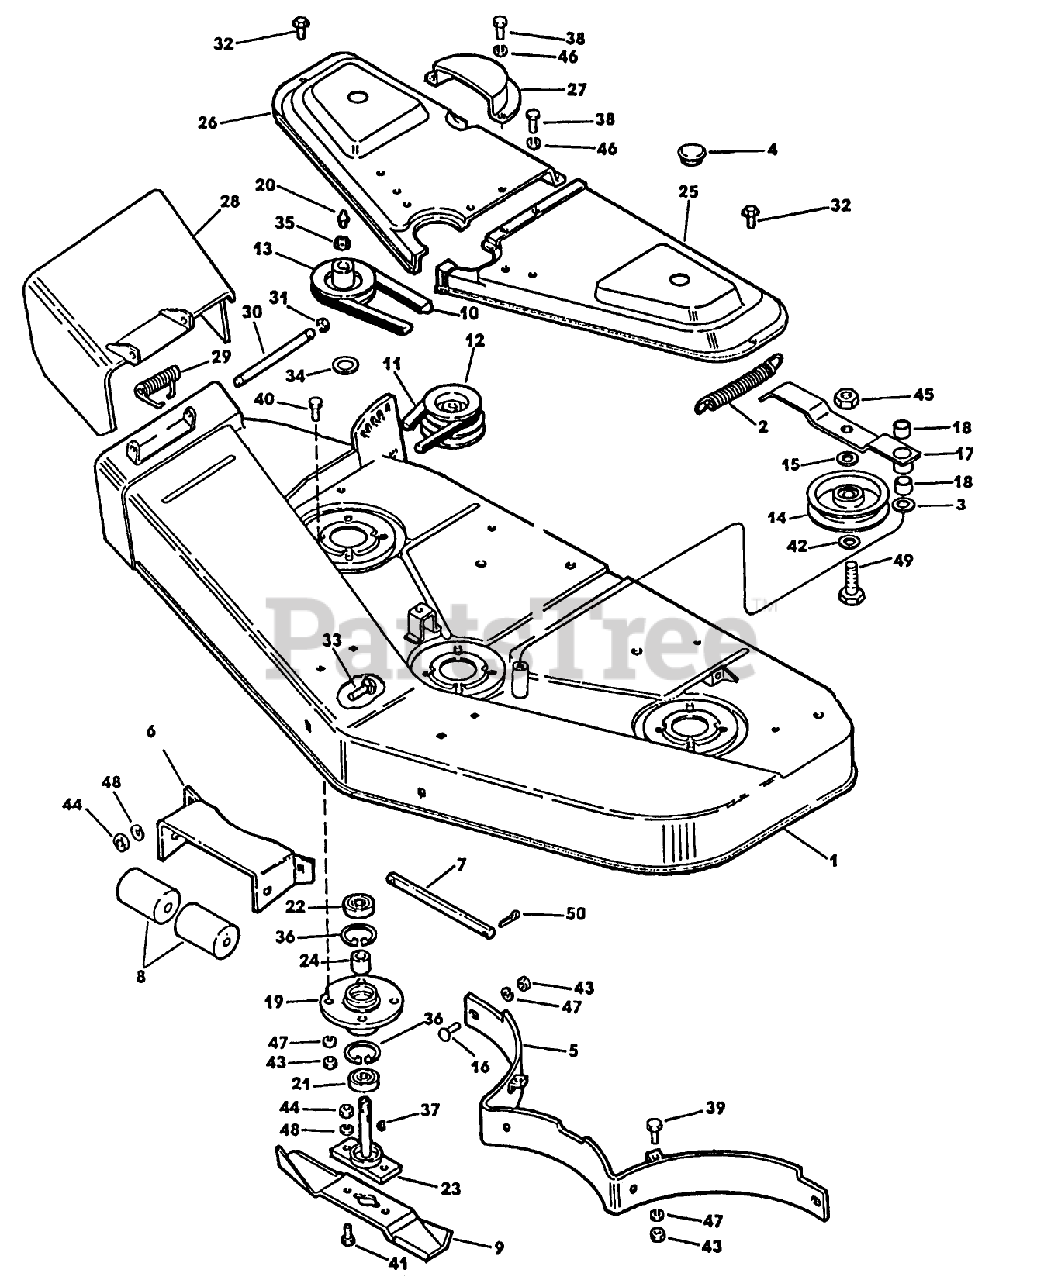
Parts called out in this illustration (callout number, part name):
2	SPRING
4	PLUG - BELT COVER
7	SHAFT
8	ROLLER
10	V-BELT
11	V-BELT T
14	PULLEY - IDLER
18	BEARING-SLEEVE
19	HOUSING-SPINDLE S
23	SPINDLE ASSEMBLY
29	SPRING - CHUTE
30	SHAFT - CHUTE
31	E-RING
32	SCREW-THREAD FRMG
33	BOLT - CARRIAGE
34	SPACER
35	LOCKNUT-SPECIAL
38	SCREW-HH
39	SCREW - HEX
40	SCREW
43	NUT SS
44	NUT
48	WASHER
